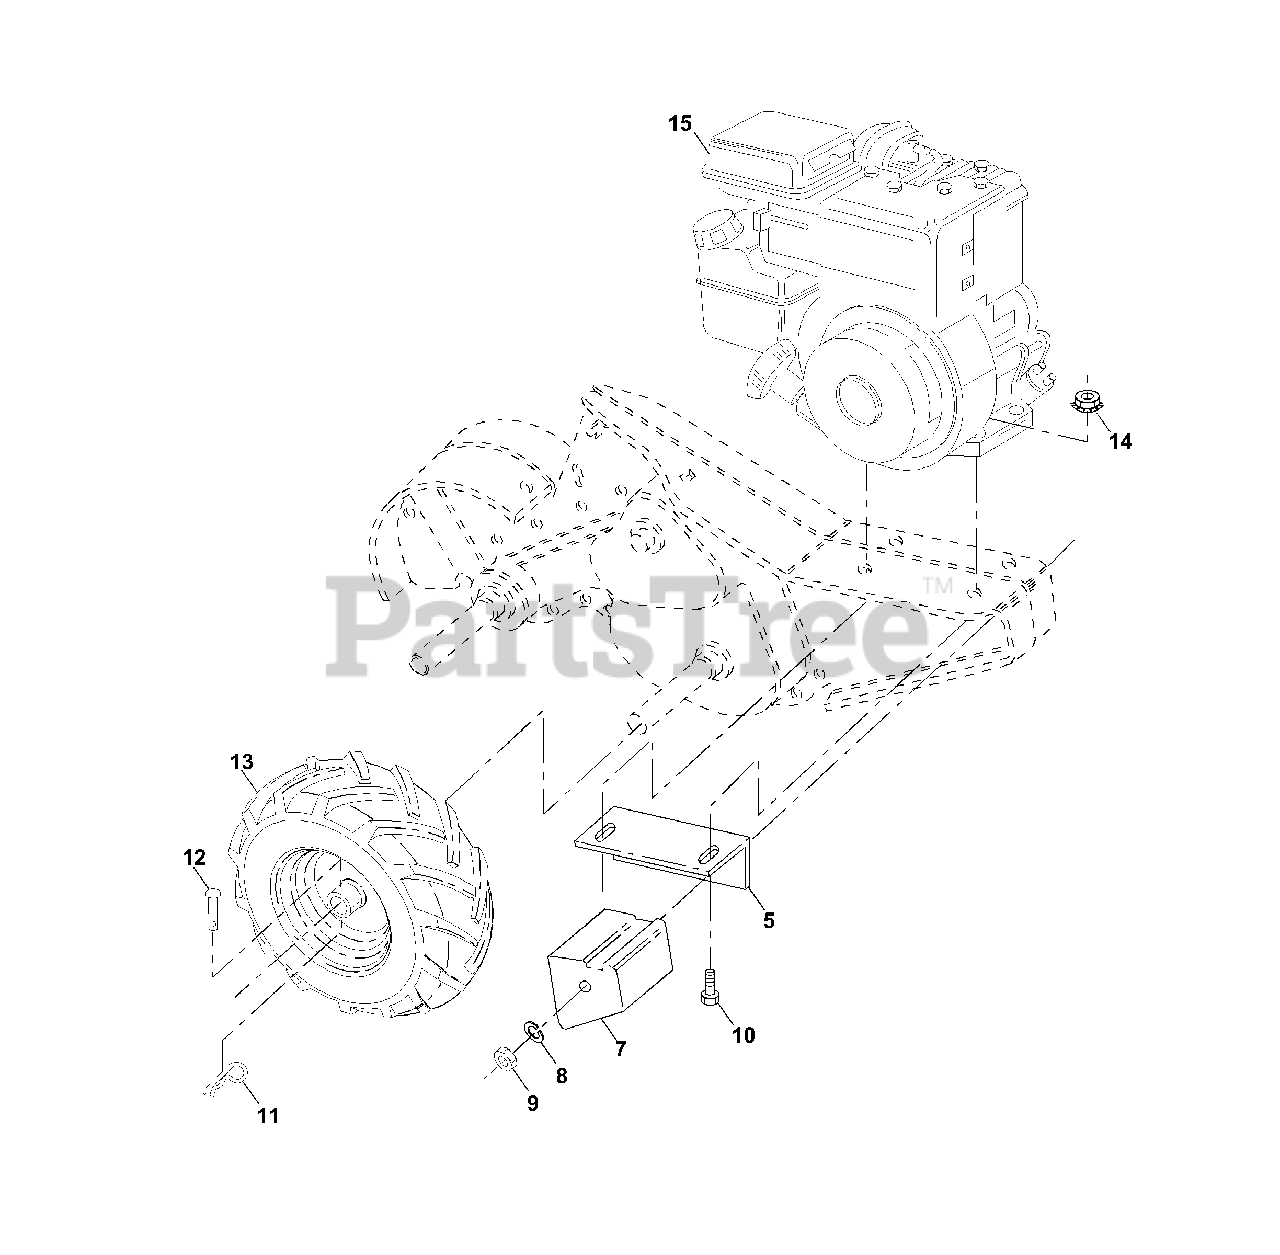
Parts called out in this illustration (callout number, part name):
5	Bracket, Reinforcement
6	Bolt, Hex 5/16-18 x 1-1/2
7	Counter Weight, R.H.
8	Washer, Lock 3/8
9	Nut, Hex 3/8-16
11	Clip, Hairpin
12	Rivet, Drilled
13	Tire
13	Tire Valve
14	Nut, Keps 5/16-18
